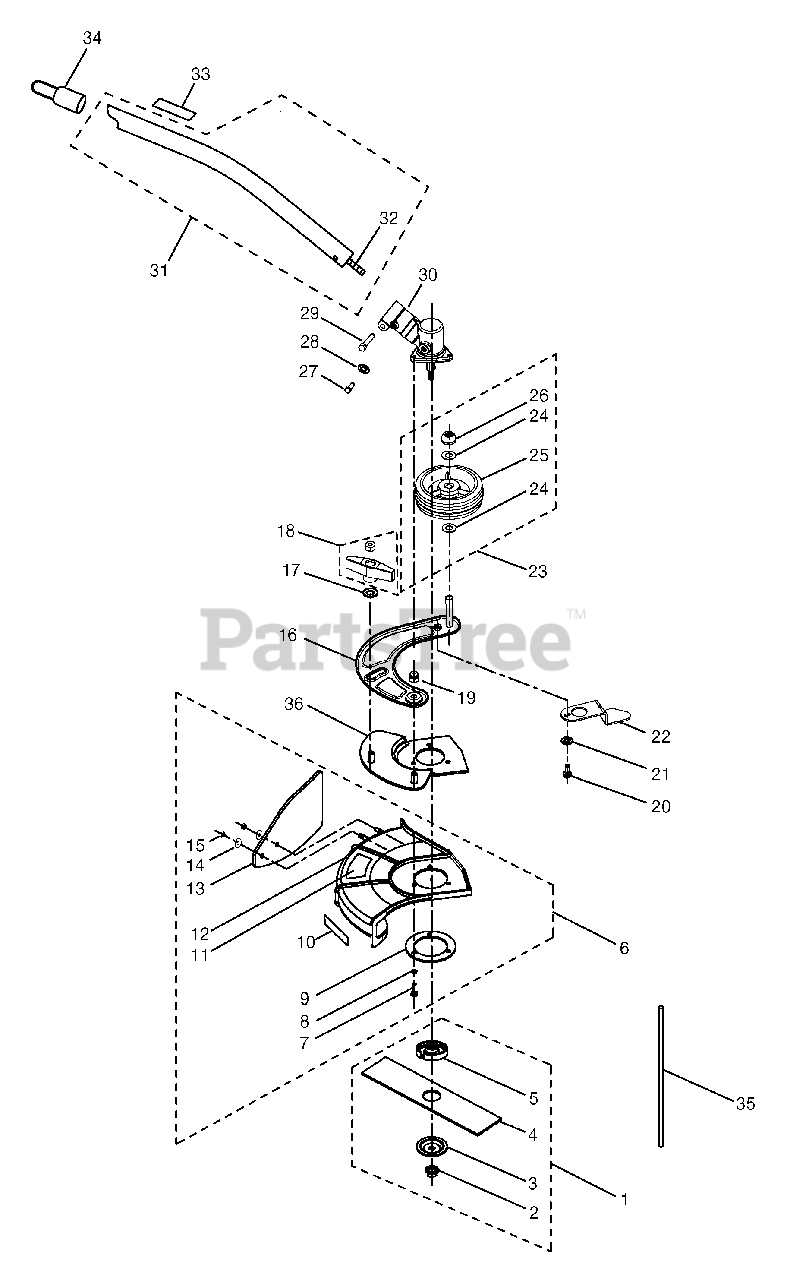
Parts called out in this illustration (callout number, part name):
1	BLADE ASSEMBLY
2	LOCK NUT (M8)
3	WASHER, CUPPED
4	BLADE, EDGER
5	WASHER, FLANGE
6	BLADE GUARD ASSEMBLY
7	SCREW (10-24 X 5/8 in.)
8	WASHER, HELICAL LOCK #10
10	DECAL, WARNING
11	DECAL, EXPAND-IT
12	BLADE GUARD
13	DRAG FLAP
14	WASHER, FLAT (6mm)
15	NUT, HEX (M6)
16	SUPPORT ARM
17	WASHER, FLAT (10mm)
18	KNOB ASSEMBLY
19	NUT, HEX W/NYLON CAP (M8)
20	SCREW, (M5 X 16mm, HEX)
21	WASHER, FLAT
22	CURB GUIDE
23	WHEEL ASSEMBLY
24	WASHER, FLAT (10mm)
25	EDGER WHEEL
26	NUT, PUSHON (10mm)
27	SCREW, (M5 X 15mm, HEX HD.)
28	WASHER, FLAT
29	SCREW, (M6 X 30mm, HEX HD.)
30	GEARHEAD ASSEMBLY W/SCREWS
31	DRIVESHAFT ASSEMBLY
32	FLEXIBLE SHAFT
33	WARNING LABEL
34	END CAP
35	HOLDING PIN
36	PLATE AND STUD
